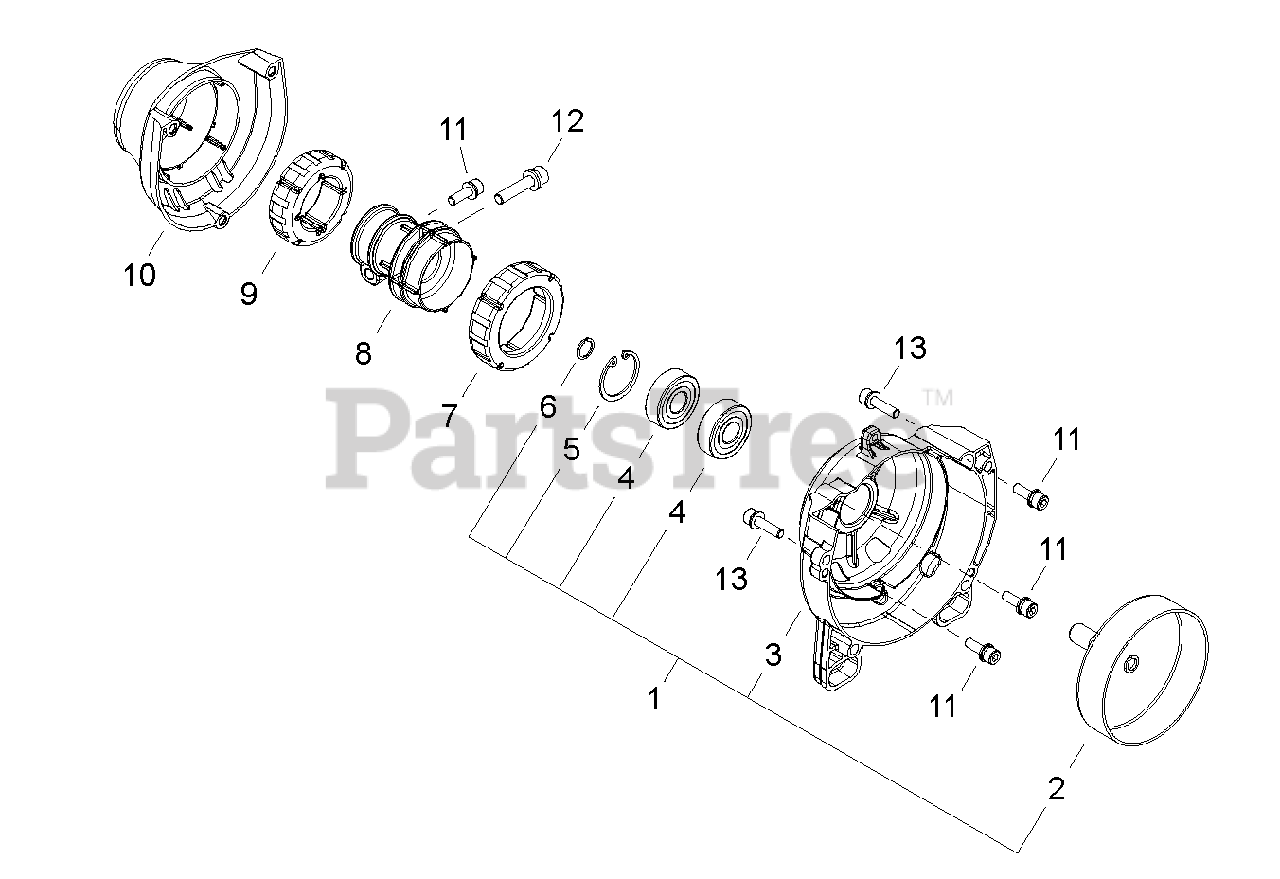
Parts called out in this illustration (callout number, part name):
1	FAN CASE ASSY
2	DRUM, CLUTCH
3	CASE, FAN
4	BEARING, BALL - 6001DDUC3
5	RING, RETAINING - 28
6	RING, RETAINING
7	CUSHION - REAR
8	CUSHION
9	CUSHION - FRONT
10	COVER, CUSHION
11	SCREW - 5X16
12	SCREW - 6X28
13	SCREW - 5X20
